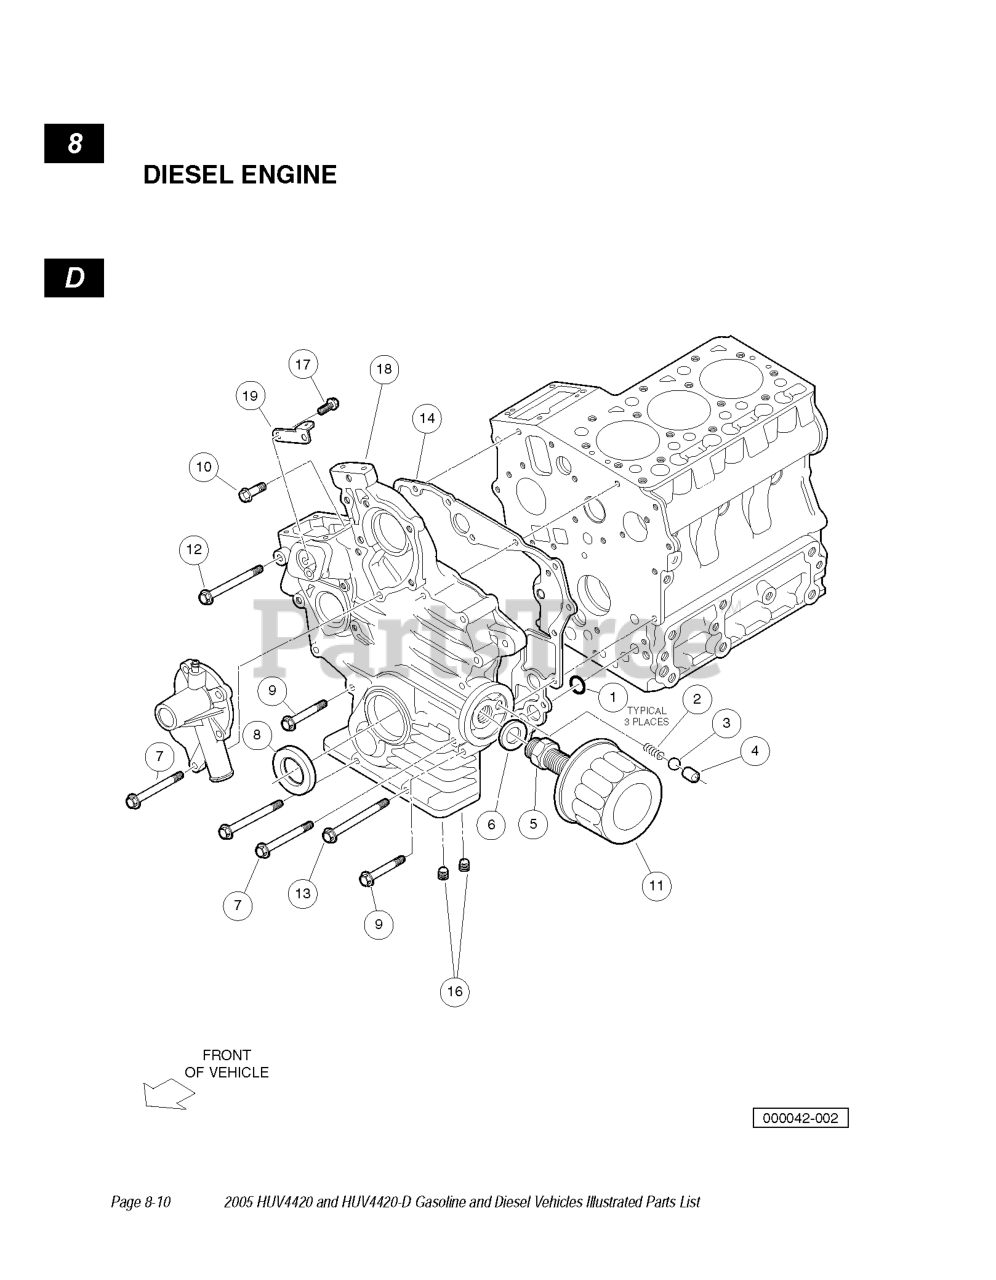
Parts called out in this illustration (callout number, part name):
1	O-RING, 18 X 13
2	SPRING, VALVE
3	BALL, VALVE
4	SEAT, VALVE
5	JOINT, PIPE
6	WASHER, PLAIN, SPECIAL
7	BOLT, M6 X 1 X 60
9	BOLT, D722, FRONT CASE
10	BOLT, D722 INTAKE MANFLD LOWER
11	FILTER, ENGINE OIL,D722
12	BOLT, GEARCASE, TOP
13	BOLT, GEARCASE, LOWER
14	GASKET, GEARCASE, D722
15	CASE-GEAR-COMP
16	PLUG, 1/4" NPT
19	STAY-SPRING-START
